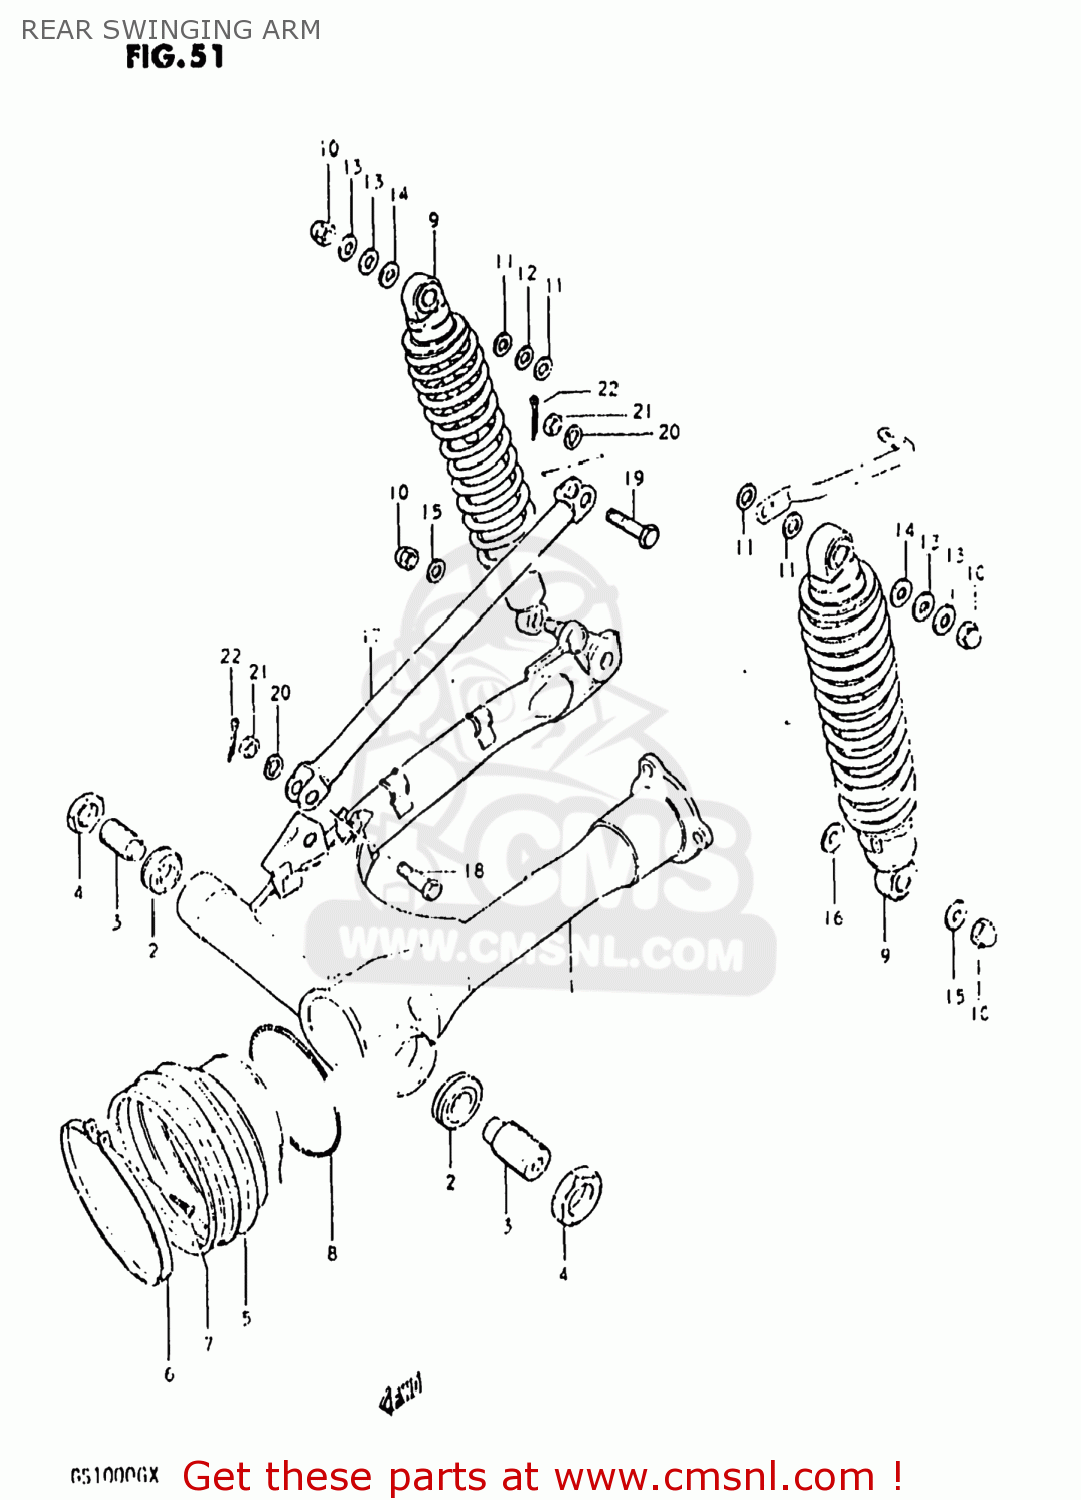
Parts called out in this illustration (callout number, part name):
1	SWING ARM ASSEMBLY,REAR
2	BEARING(17X40X13.25)
3	BOLT,REAR SWING ARM PIVOT
4	NUT
5	BOOT,PROPELLER SHAFT
6	CLAMP
7	SCREW 4X25
8	SPRING,PROPELLER SHAFT
9	ABSORBER ASSEMBLY,REAR SHOCK
10	NUT, LOWER LH
11	WASHER
12	WASHER (12.5X24X3.2)
13	WASHER
14	WASHER(10.5X24X3.2)
15	WASHER
16	WASHER
17	LINK,REAR TORQUE
18	BOLT
19	BOLT(10X39)
20	WASHER
21	NUT
22	PIN 20X20
